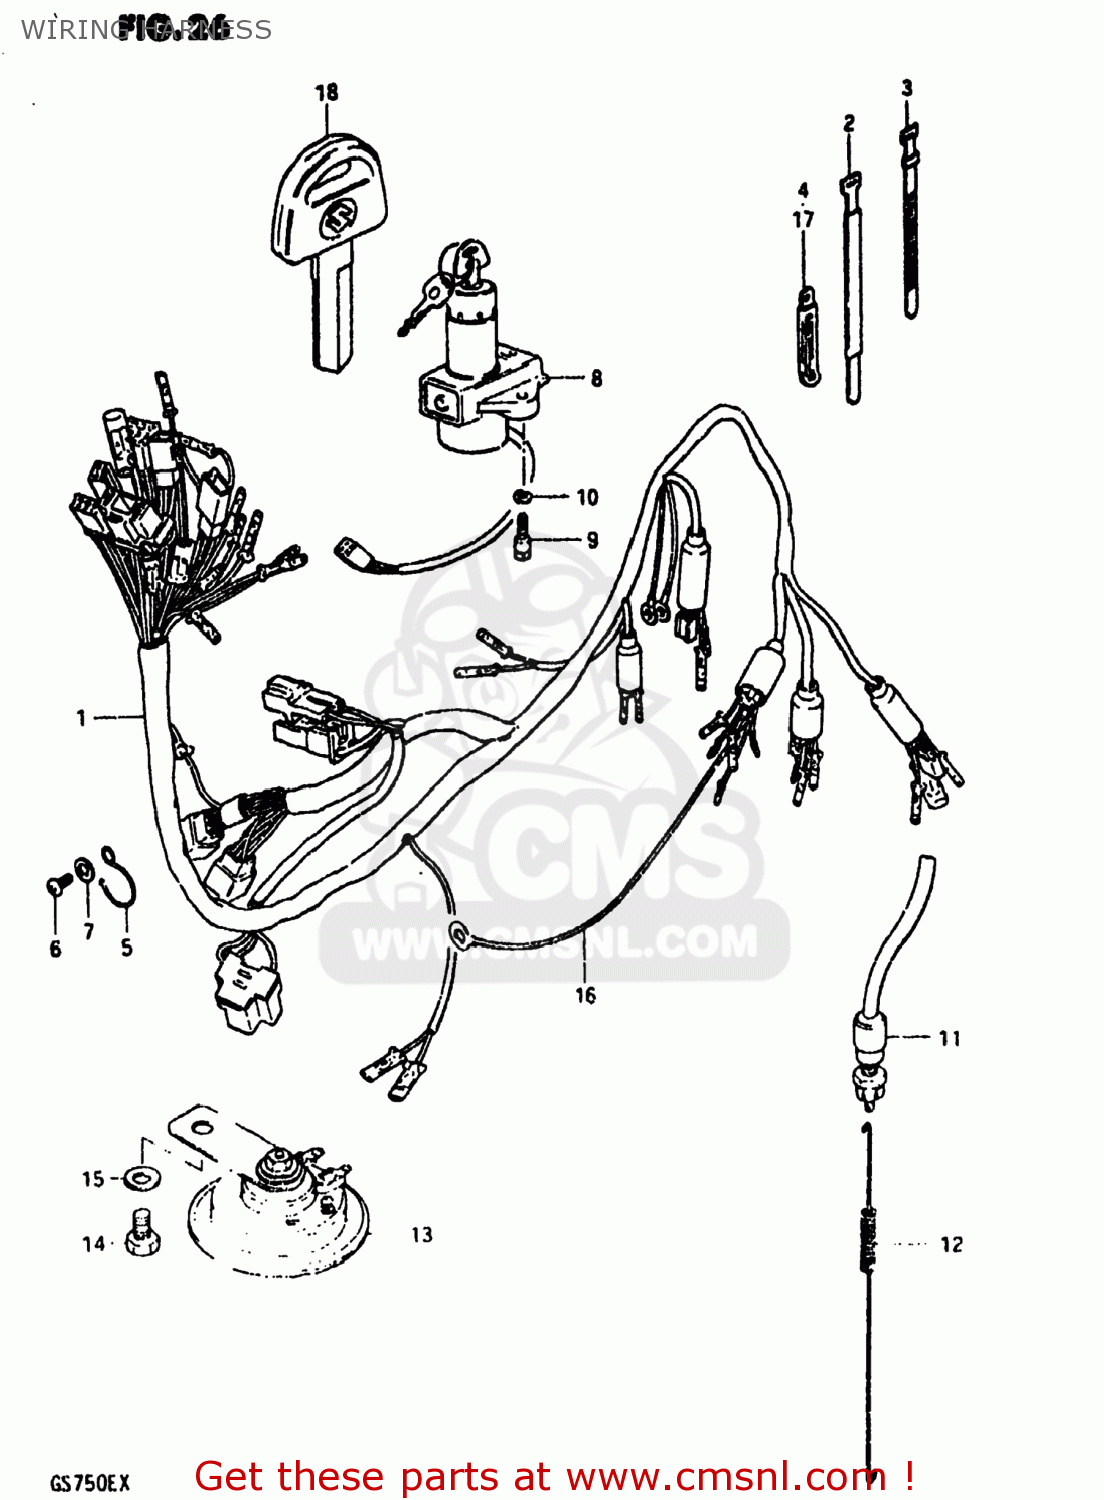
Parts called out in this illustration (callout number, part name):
1	HARNESS,WIRING
2	CLAMP
3	CLAMP(L:120)
4	CLAMP
5	GUIDE,WIRING HARNESS
6	SCREW 6X12
7	WASHER
8	SWITCH ASSY,IGNITION
9	BOLT
10	LOCK WASHER
11	SWITCH ASSEMBLY,STOP LAMP
12	SPRING
13	HORN ASSEMBLY,LOW PITCH
14	BOLT 8X12
15	WASHER
16	WIRE
17	CLAMP
18	KEY,BLANK
